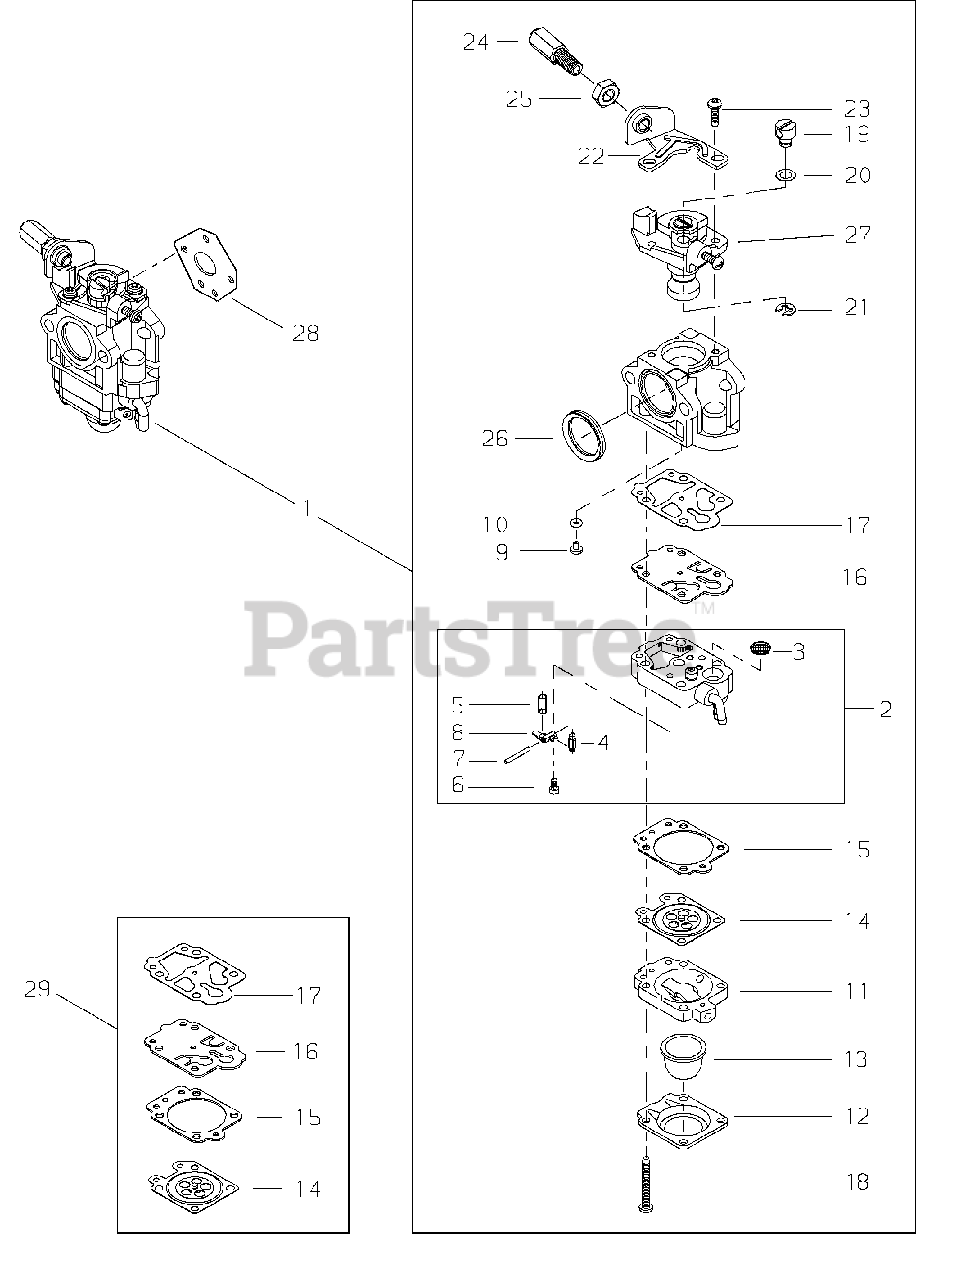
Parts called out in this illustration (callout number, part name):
1	CARBURETOR
2	BASE, PURGE
3	STRAINER
4	VALVE, NEEDLE
5	SPRING, METERING LEVER
6	SCREW, METERING LEVER PIN
7	PIN, METERING LEVER
8	LEVER, METERING
9	JET, MAIN
11	BASE, PURGE
12	COVER, PUMP
13	BULB, PURGE
14	DIAPHRAGM, METERING
15	GASKET, METERING
16	DIAPHRAGM, PUMP
17	GASKET, PUMP
21	RING, RETAINING
22	BRACKET, CABLE
24	NUT, CABLE ADJUST
26	SEAL
27	THROTTLE VALVE ASSY
28	GASKET, INTAKE
29	DIAPHRAGM/GASKET KIT
